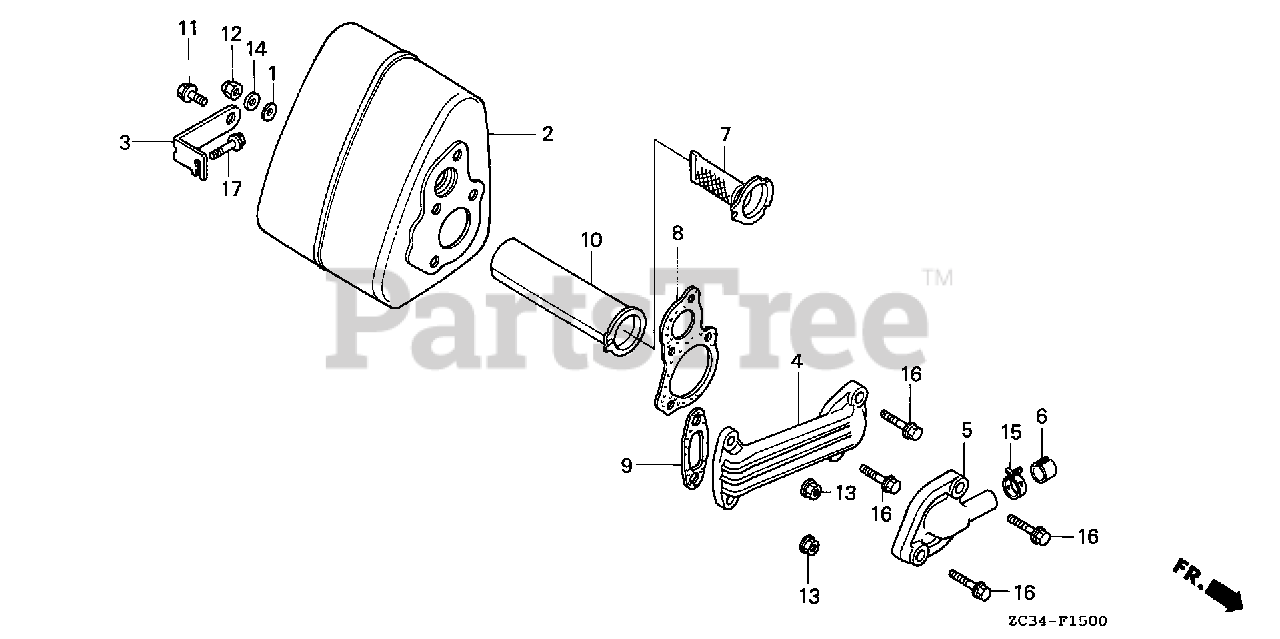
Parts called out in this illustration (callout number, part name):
1	GASKET, MUFFLER PROTECTOR
3	STAY, MUFFLER
5	DEFLECTOR, MUFFLER
7	ARRESTER, SPARK
8	GASKET, MUFFLER
9	GASKET, EX. PIPE
10	PIPE, TAIL
11	BOLT, FLANGE (6X10)
12	NUT, CAP (5MM)
13	NUT, FLANGE (5MM)
14	WASHER, PLAIN (5MM)
15	CLAMP, TUBE (D12.5)
16	BOLT, FLANGE (6X25)
17	BOLT, FLANGE (6X10)
